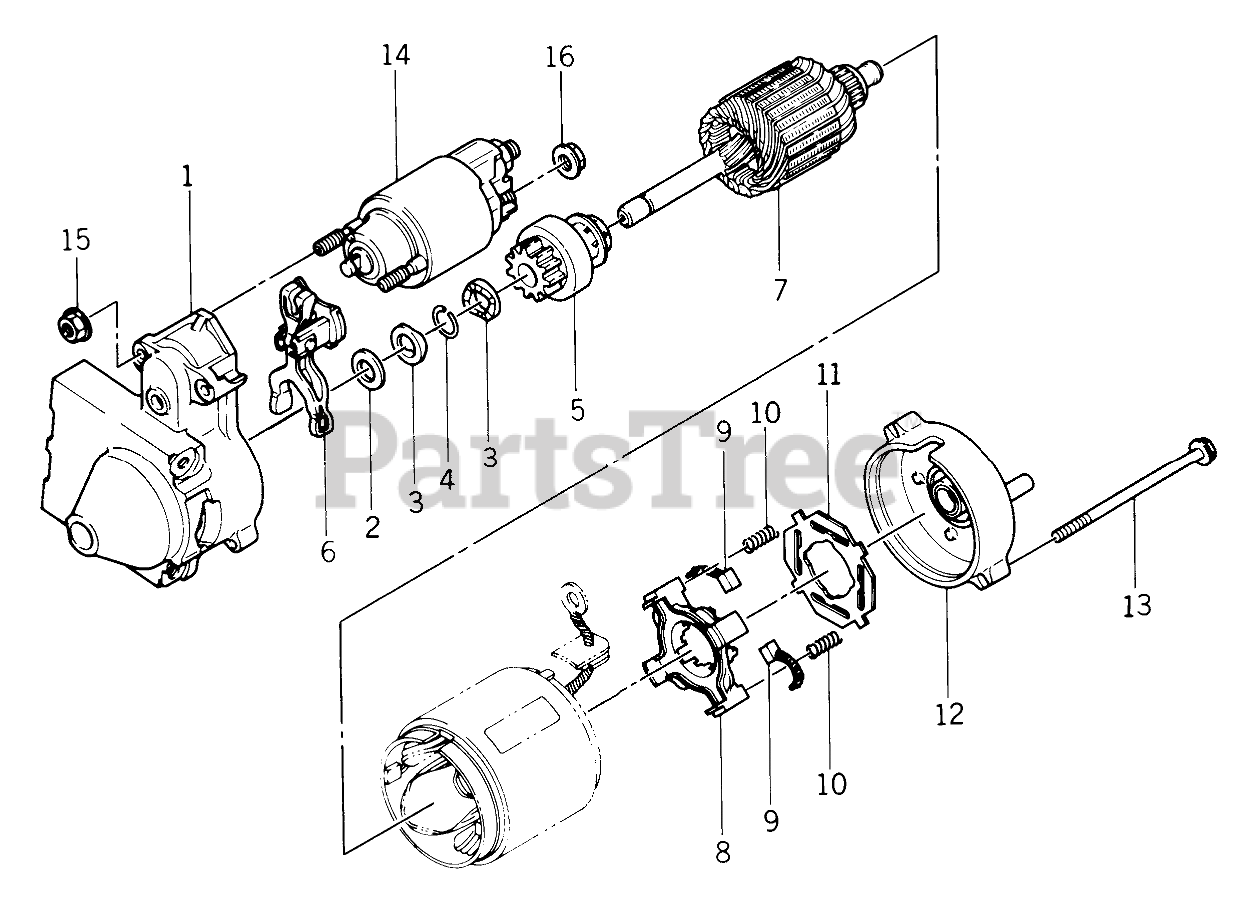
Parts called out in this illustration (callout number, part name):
1	COVER ASSY
2	WASHER
3	STOPPER
4	RING-SNAP
5	CLUTCH ASSY
6	LEVER-SHIFT
7	ARMATURE
8	HOLDER-BRUSH
9	BRUSH
10	221040-2052 Brush Spring
11	316073-2098 Insulatory
12	316073-2098 Insulatory
14	SWITCH ASSY
